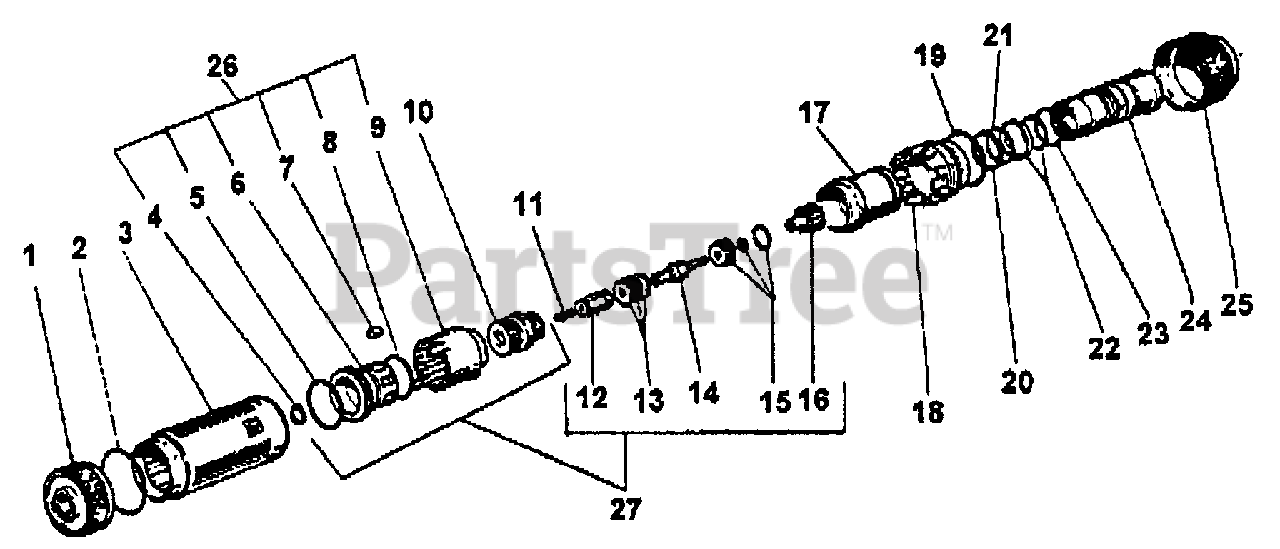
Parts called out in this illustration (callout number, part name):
1	CAP, FRONT
2	O-RING 33 05×1 78
3	KNOB
4	RING, SNAP
5	O-RING
6	ROTOR
7	BEARING, ROLLER
8	O-RING 0.797×.103
9	CLUTCH
10	NUT
11	NOZZLE - RED
12	HOLDER, NOZZLE
13	BEARING, BALL
14	CRANKSHAFT ASSY
15	SEAL
16	ROTOR
17	CYLINDER, DIFFUSER
18	DIFFUSER, LOW PRESSURE
19	O-RING 28 25×2 62
20	RING, ANTI-EXTRUSION
21	O-RING 20 35×1 78
22	SEAL
23	O-RING 18 72×2 62 VITON
24	BODY, DIFFUSER
25	RING, LOCKING
26	KIT, (PARTIAL) ROTOX REBUILD
27	KIT, (COMPL.) ROTOX REBUILD
